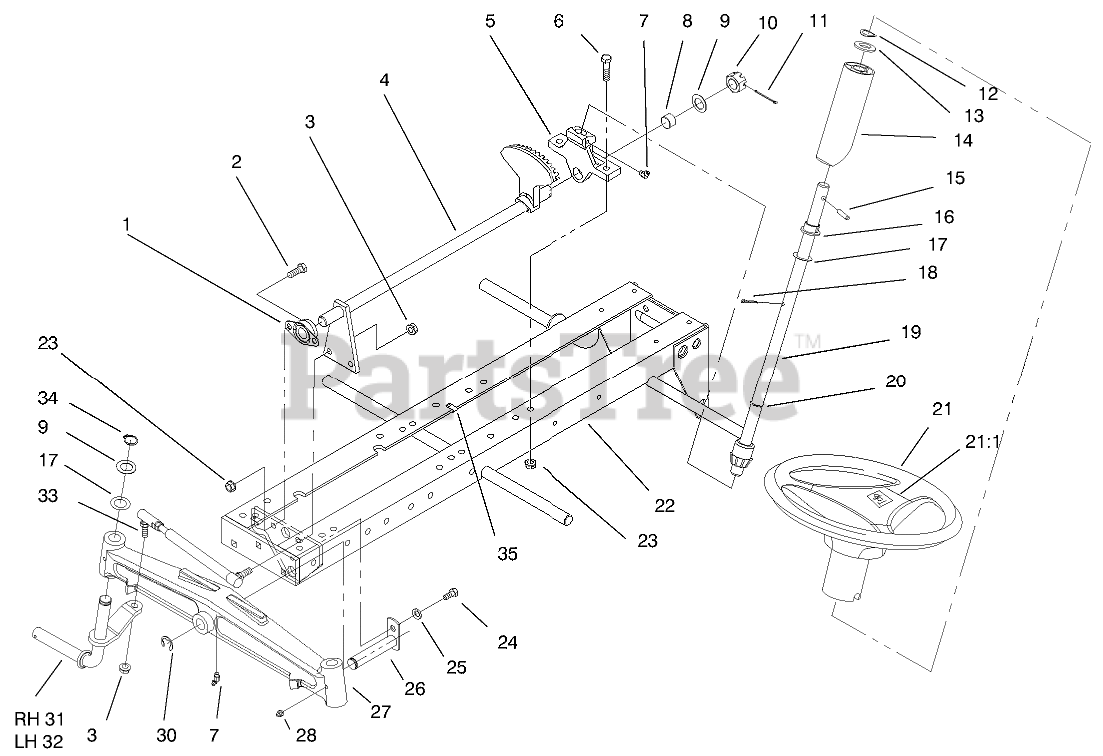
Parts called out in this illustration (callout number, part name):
1	BEARING-FLANGED
2	SCREW-HH
3	NUT-LOCK
4	Shaft-Steering
5	Support-Lower Steering
6	SCREW-HH
7	FITTING-LUBE, 45 DEG
8	BEARING-BRONZE
9	WASHER
10	NUT-HEX, SLOTTED
11	PIN-COTTER
12	WASHER-BOWED
13	WASHER-FLAT
14	TUBE-STEERING
15	PIN-ROLL
16	BEARING-FLANGED
17	WASHER-SHIM
18	PIN-COTTER
19	STEERING SHAFT ASM
20	O-RING
21	WHEEL - STEERING 15"
21:1	COVER-WHEEL
22	FRAME ASM
23	NUT-LOCK, NI
24	SCREW-HH
25	WASHER-LOCK
26	PIN AND PLATE ASM
27	AXLE-FRONT
28	FITTING-GREASE
30	E-RING
31	LH SPINDLE ASM
32	RH SPINDLE WA
33	ASM-Rod
34	RING-RETAINING
35	CLIP-WIRE
